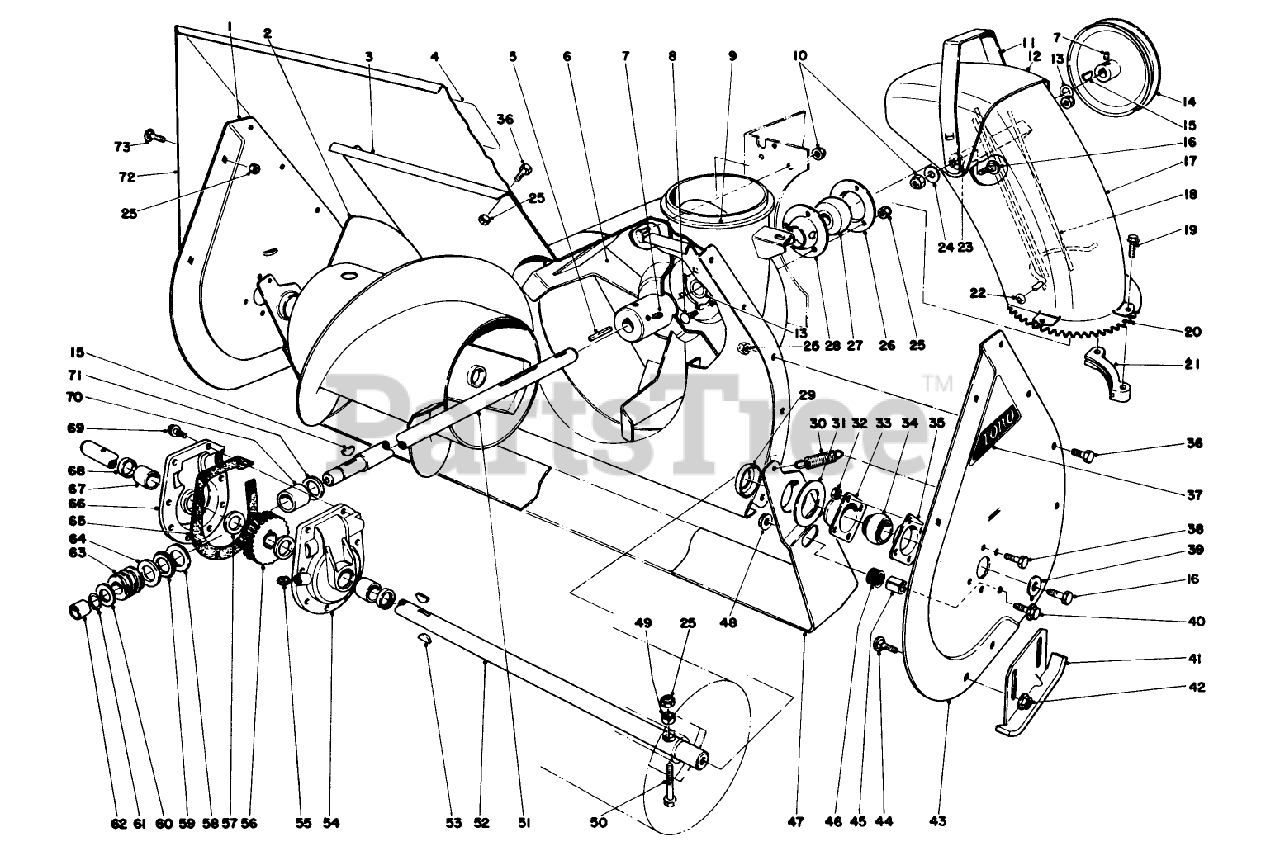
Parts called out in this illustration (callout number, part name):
1	Sideplate Auger Right
2	Auger Right
3	Auger Housing
4	Decal-Auger Warning
6	IMPELLER WA RO
7	SCREW-SET, SQH
8	BOLT-CARR
9	CHUTE RING
10	NUT-LOCK, CONE
11	DEFLECTOR HANDLE B
12	Chute Deflector
13	WASHER
14	IMPELLER PULLEY
15	KEY-WOODRUFF
16	SCREW-HH
17	Chute
18	Chute Guard
19	SPECIAL SCREW
20	Chute Swivel Gear
21	CHUTE RETAINER
22	NUT-PUSH
23	WASHER-RUBBER
24	WASHER-BELLEVILLE
25	NUT-LOCK, NI
26	FLANGE-CUP, BEARING
27	Ball Bearing
28	FLANGE-CUP, BEARING
29	Positioner-Scraper
30	SPRING-TENSION
31	SCRAPER BLADE SPACER
32	NUT-LOCK, CONE
33	BEARING-FLANGE, FRONT
34	BEARING
35	BEARING-FLANGE, REAR
36	SCREW-HH
37	AUGER SIDE PLT DECAL
38	SCREW-HH
39	WASHER
40	SCREW-HHF
41	AUGER SKID WA R
42	NUT-HHF, WHIZ
43	Sideplate Auger Left
44	SCREW-CARR
45	SCRAPER STOP SPACER
46	SCRAPER STOP CUSHION
47	24 SCRAPER BLD
48	NUT-HF
49	SPACER-HUB, AUGER
50	Auger Bolt
51	Shaft Impeller
52	24 AUGER SHAFT
53	KEY-WOODRUFF
54	Gear Case (Incl. Ref. #67 & 68)
55	PLUG-PIPE, SQH
56	GEAR-WORM, 27T
57	WASHER-THRUST
58	WASHER-THRUST
59	BEARING-THRUST
60	WASHER-THRUST
61	Ring-Snap
62	BUSHING
64	THRUST-WASHER
65	Gasket
66	Gear Case (Incl. Ref. #67 & 68)
67	BUSHING
68	SEAL-OIL
69	SCREW-HWHTF
70	BUSHING-SPECIAL
71	RING-QUAD
72	AUGER EXT 24 SCND R
73	SCREW-CARR
